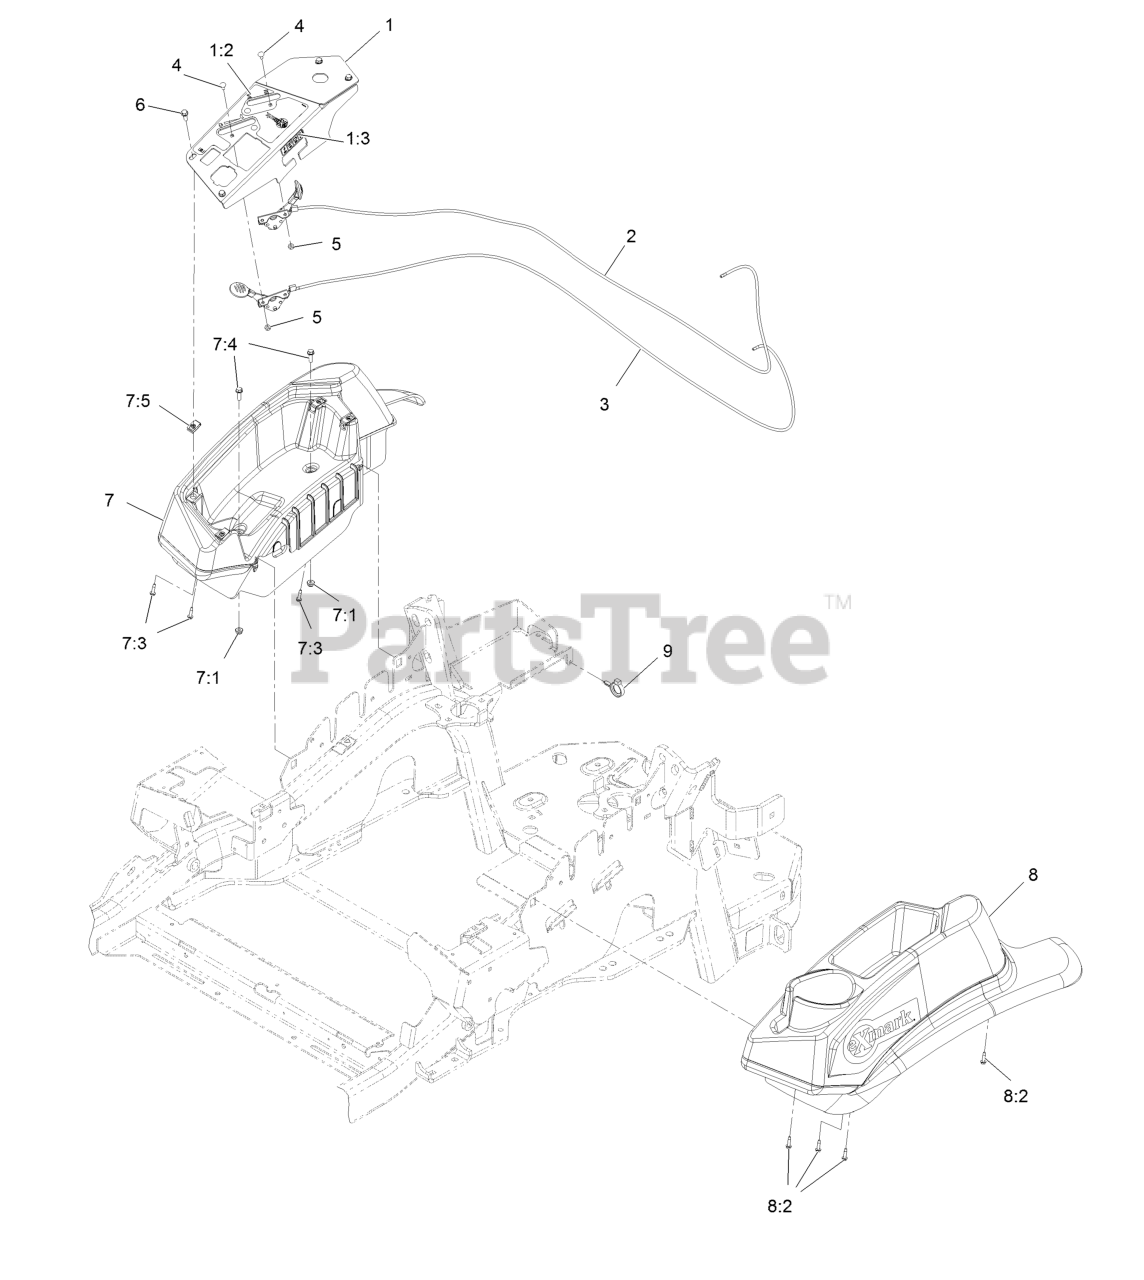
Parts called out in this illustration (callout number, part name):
1	CONSOLE,PANEL W/DECAL
1:2	DECAL-CONTROL PANEL NON-E
1:3	DECAL-FUSES
2	ASM, CHOKE CABLE
3	ASM,THROTTLE CABLE
4	BOLT-CARR
5	NUT-LOCK, NI
6	SCREW-HWH
7	CONSOLE,RH NARROW ASM
7:3	SCREW,THD FORM,HWH
7:4	SCREW-HWH
7:5	Nut-Retainer-Panel 1/4-20
8	CONSOLE.LH NARROW ASM
8:2	SCREW,THD FORM,HWH
9	CLAMP-HOSE
